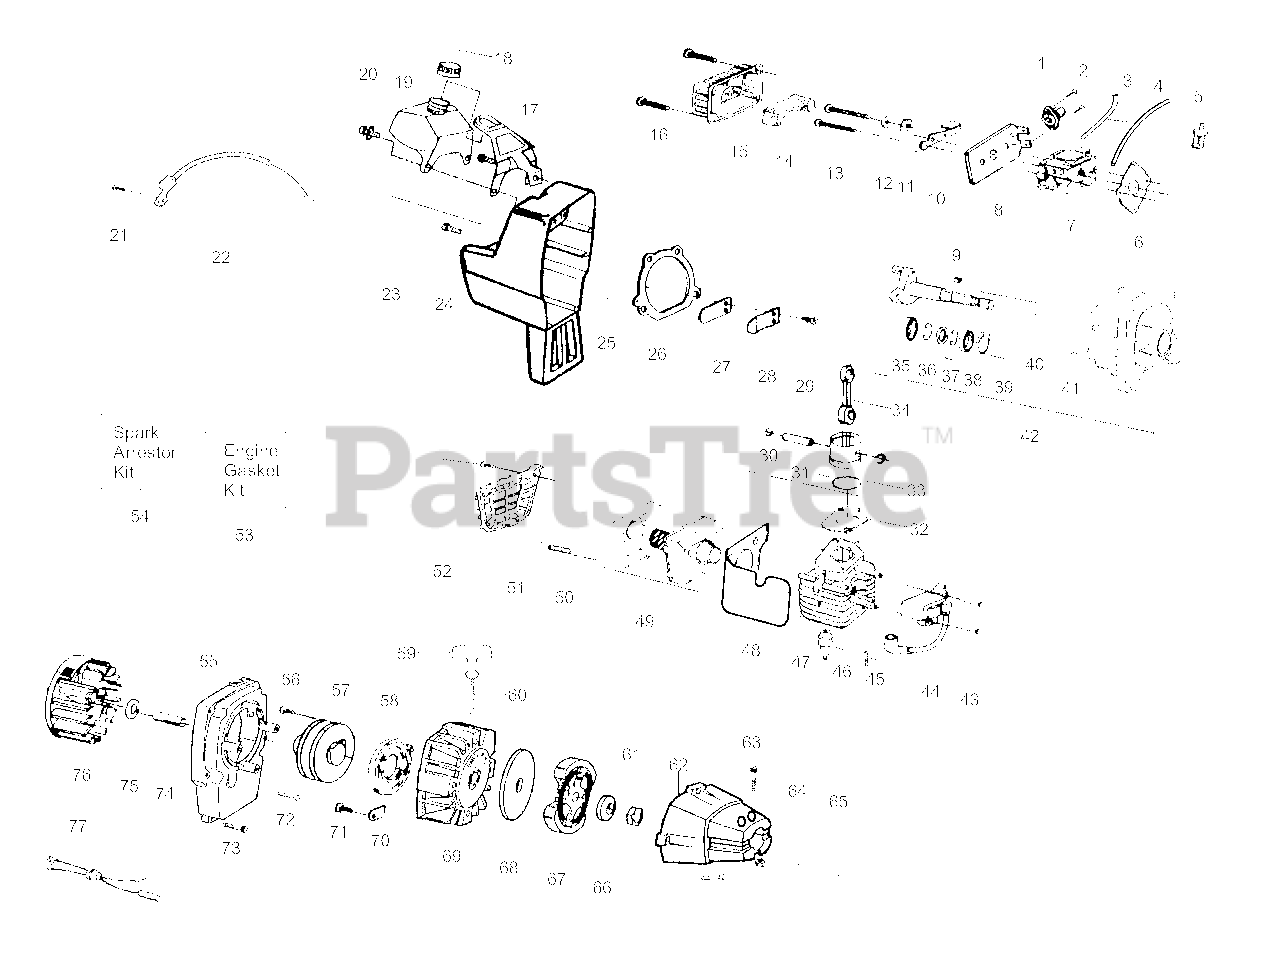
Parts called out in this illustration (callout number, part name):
1	Assy-Bulb
3	Kit-Fuel Line (small)
4	Kit-Fuel line (large)
5	Assy-Fuel Pick-up
6	Gasket-Carburetor
7	Kit-Carburetor Ass'y.
8	Plate-Air Filter
9	Key-Flywheel
10	Shutter-Choke
12	Spacer-Choke
14	Filter-Air
15	Cover-Air Filter
17	Bracket-Fuel Tank
18	Assy-Fuel Cap
19	Assy-Fuel Tank
22	Throttle Cable
26	Gasket-C'case/Shroud
27	Reed Valve
28	Stop-Reed
30	Retainer-Piston Pin
31	Ring-Piston
32	Gasket-Cylinder
33	Kit-Piston
34	Assy-Connecting Rod
35	Bearing-Inner
36	Ring-Retaining
37	Seal-Crankshaft
38	Bearing-Outer
39	Retaining Ring-C'shaft
40	Assy-Crankshaft
41	Assy-Crankcase
42	Crankcase/Crankshaft Ass'y.
44	Ignition Module
46	Spark Plug (RCJ-6Y)
47	Kit-Cylinder
48	Heat Shield/Air Dam
49	Kit-Muffler
50	Spring-Muffler
51	Guard-Muffler
53	Kit-Engine Gasket
54	Kit-Spark Arrestor
55	Fan Housing
57	Kit-Starter Pulley
58	Spring-Starter
59	Handle-Starter
60	Kit-Rope
62	Clutch Housing
66	Washer-Bevel
67	Kit-Clutch Ass'y
68	Washer-Clutch
69	Assy-Pulley Housing
70	Retainer
74	Spacer-Clutch
76	Assy-Flywheel
77	Leadwire/Grommet Ass'y.
